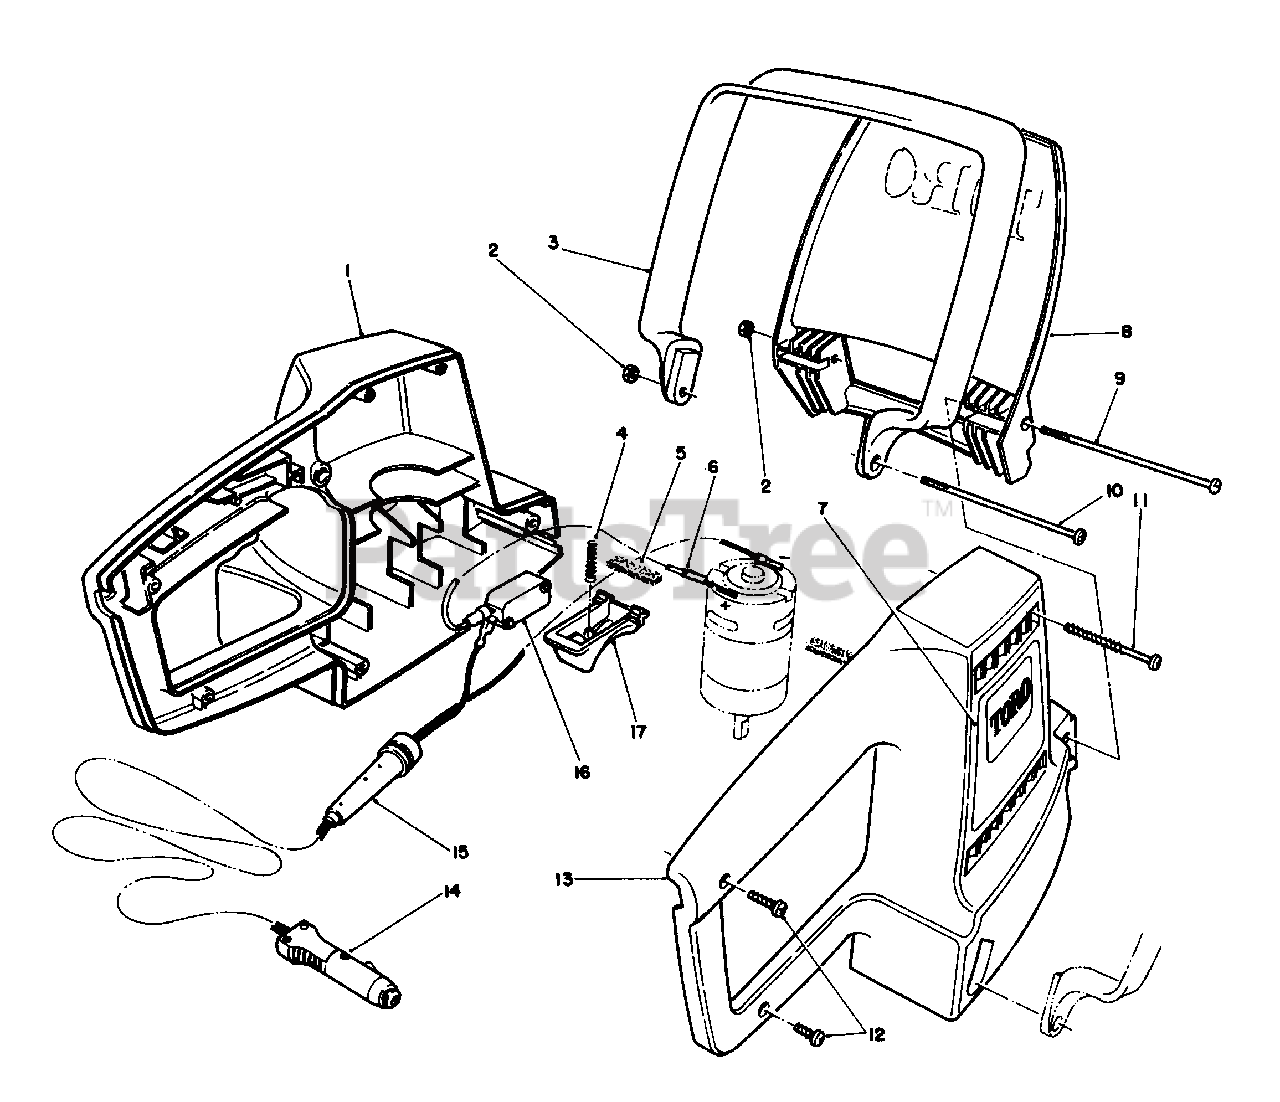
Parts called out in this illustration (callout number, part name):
1	Housing-Handle, L.H.
3	Handle-Assist
6	Wire Assembly
7	Decal-Toro
11	Screw-Thread Forming
12	Screw-Thread Forming
13	Housing-Handle, R.H.
14	Cord-Handle
15	Relief-Strain
17	Trigger-Switch
